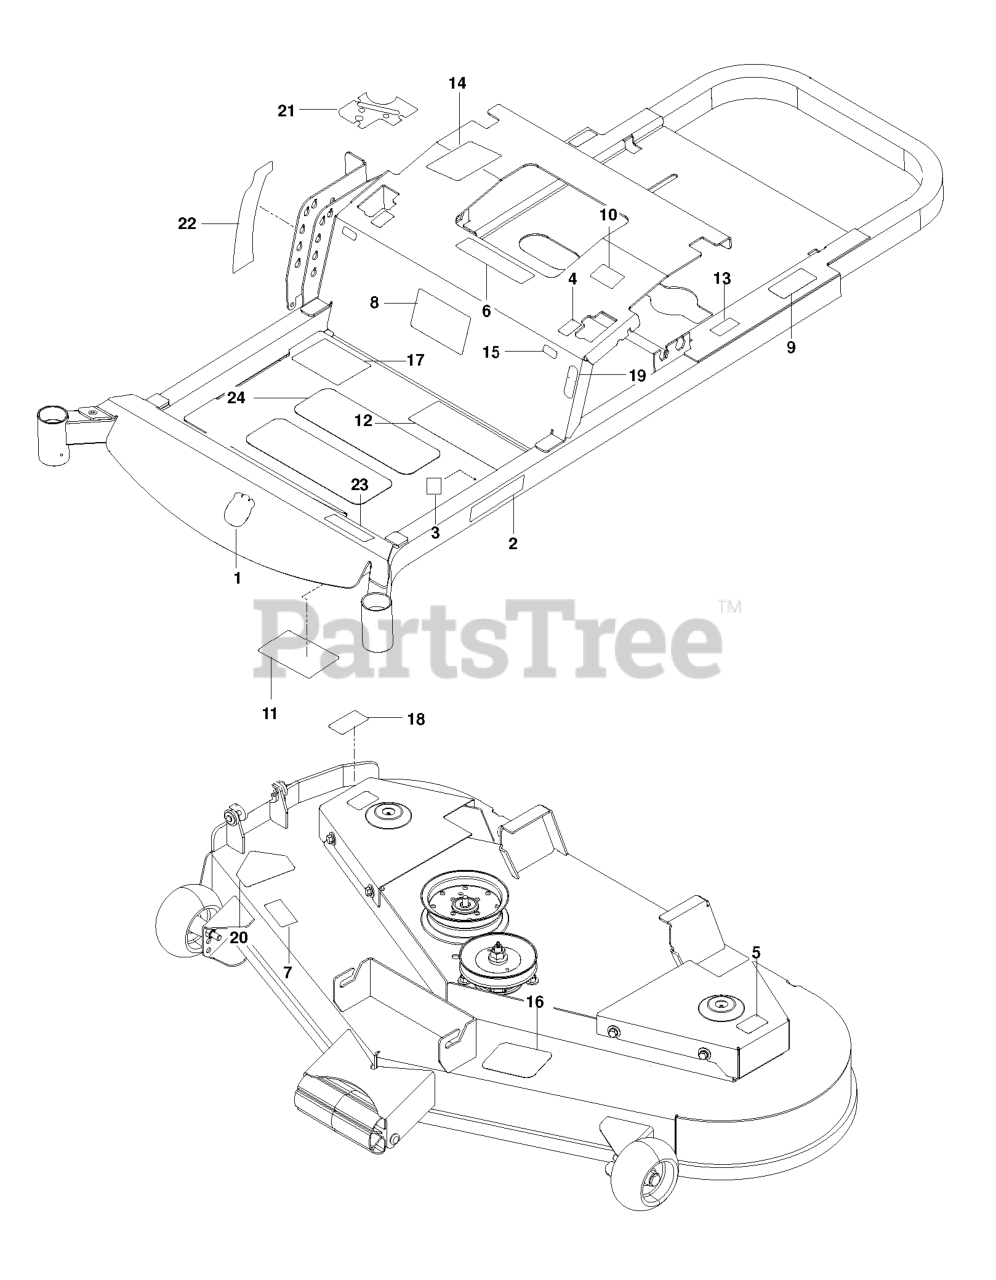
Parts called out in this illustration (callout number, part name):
1	DECAL.AUGER.HUSQ.CROWN.SNOW
2	RP.DECAL.BADGE.170MM.TEXTLOGO
3	DECAL 80 DBA
4	DECAL, MOTION CONTROL
5	DECAL.DECK.6MIL.EURO.NOSTEP
6	EURO DECAL-BATTERY WARNIN6
7	DECAL, EURO SEVERING
8	DECAL, START
9	DECAL, DO NOT TOW
10	DECAL, EXITING MOWER
11	DECAL, SERVICE
12	DECAL, SAFETY WARNING
13	DECAL, ECM, AUSTRALIA
14	DECAL, CUSTOMER RESPNSIBILITY
15	DECAL, F.S.T.
16	DECAL, BELT ROUTING
17	DECAL, WARNING
18	DECAL, CAUTION
19	DECAL, PARK BRAKE
20	DECAL, CPSC
21	DECAL, CTRL PANEL, HUSQ
22	DECAL, DECK HEIGHT, HUSQ
23	DECAL.ZTR.RZ4824TF.HUSQVARNA
24	ANTI-SKID PAD
